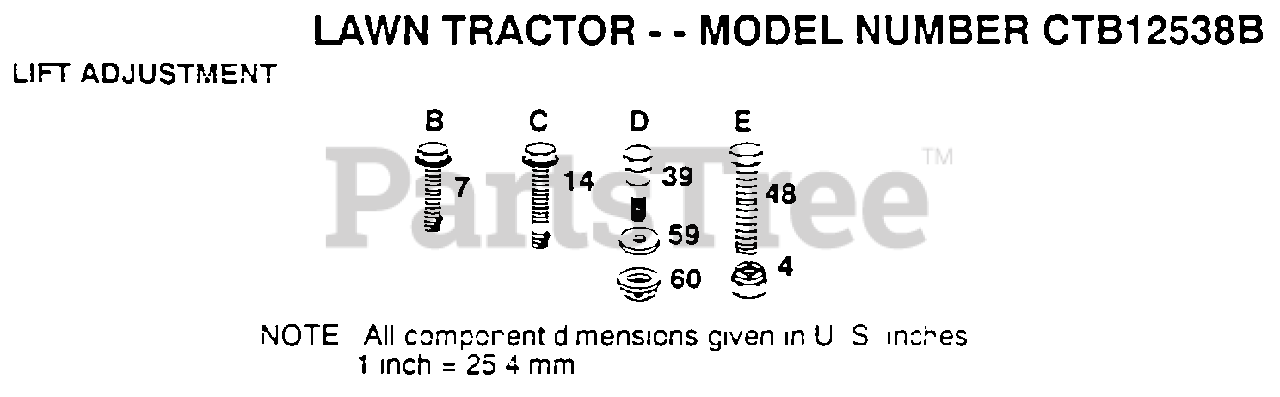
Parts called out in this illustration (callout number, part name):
7	SCREW
14	SCREW
39	"BOLT, SHOULDER LT"
59	WASHER T
60	NUT SPECIAL T
